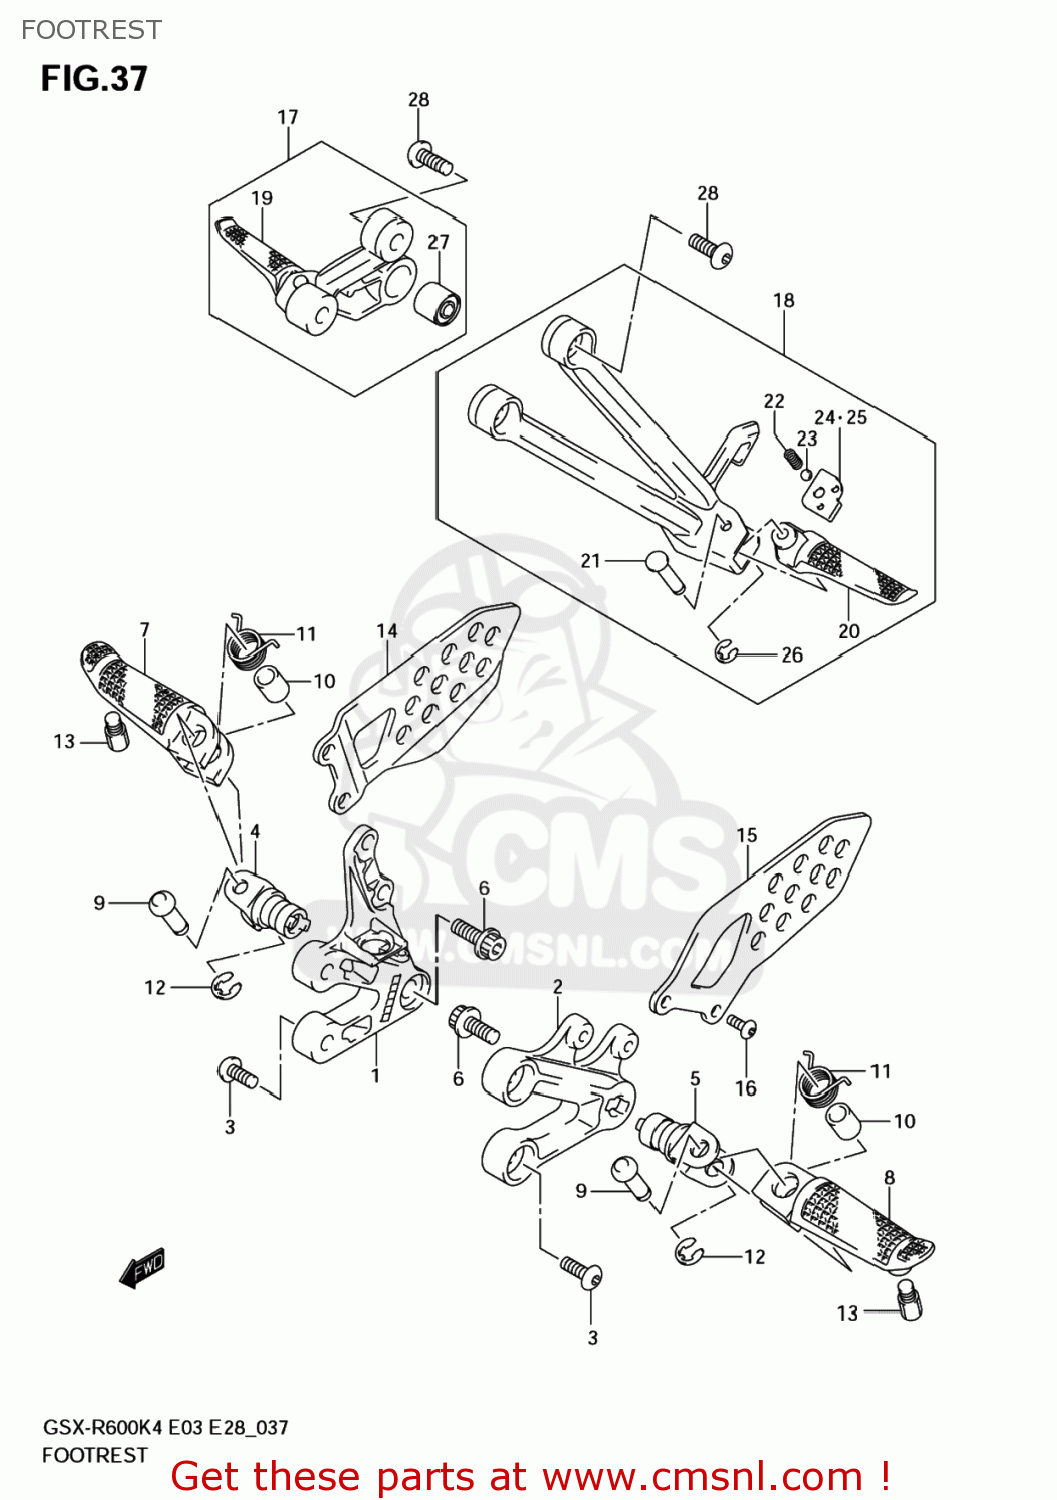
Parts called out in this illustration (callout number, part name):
1	BRACKET,FR FOOTREST,R
2	BRACKET,FR FOOTREST,L
3	BOLT(8X20)
4	HOLDER,FOOTREST,R
5	HOLDER,FOOTREST,L
6	BOLT(10X28)
7	BAR,FR FOOTREST,R
8	BAR,FR FOOTREST,L
9	PIN
10	SPACER(8.1X12X22)
11	SPRING
12	E.RING
13	BOLT,BANK SENSOR
14	GUARD,FR FOOTREST,R
15	GUARD,FR FOOTREST,L
16	SCREW,FOOTREST GUARD,L
17	FOOTREST ASSY,PILLION,R
18	FOOTREST ASSY,PILLION,L
19	BAR,PILLION FOOTREST,R
20	BAR,PILLION FOOTREST,L
21	PIN
22	SPRING
23	BALL
24	PLATE,PILLION FOOT,R
25	PLATE,PILLION FOOT,L
26	E-RING
27	BUSH
28	BOLT(8X23)
